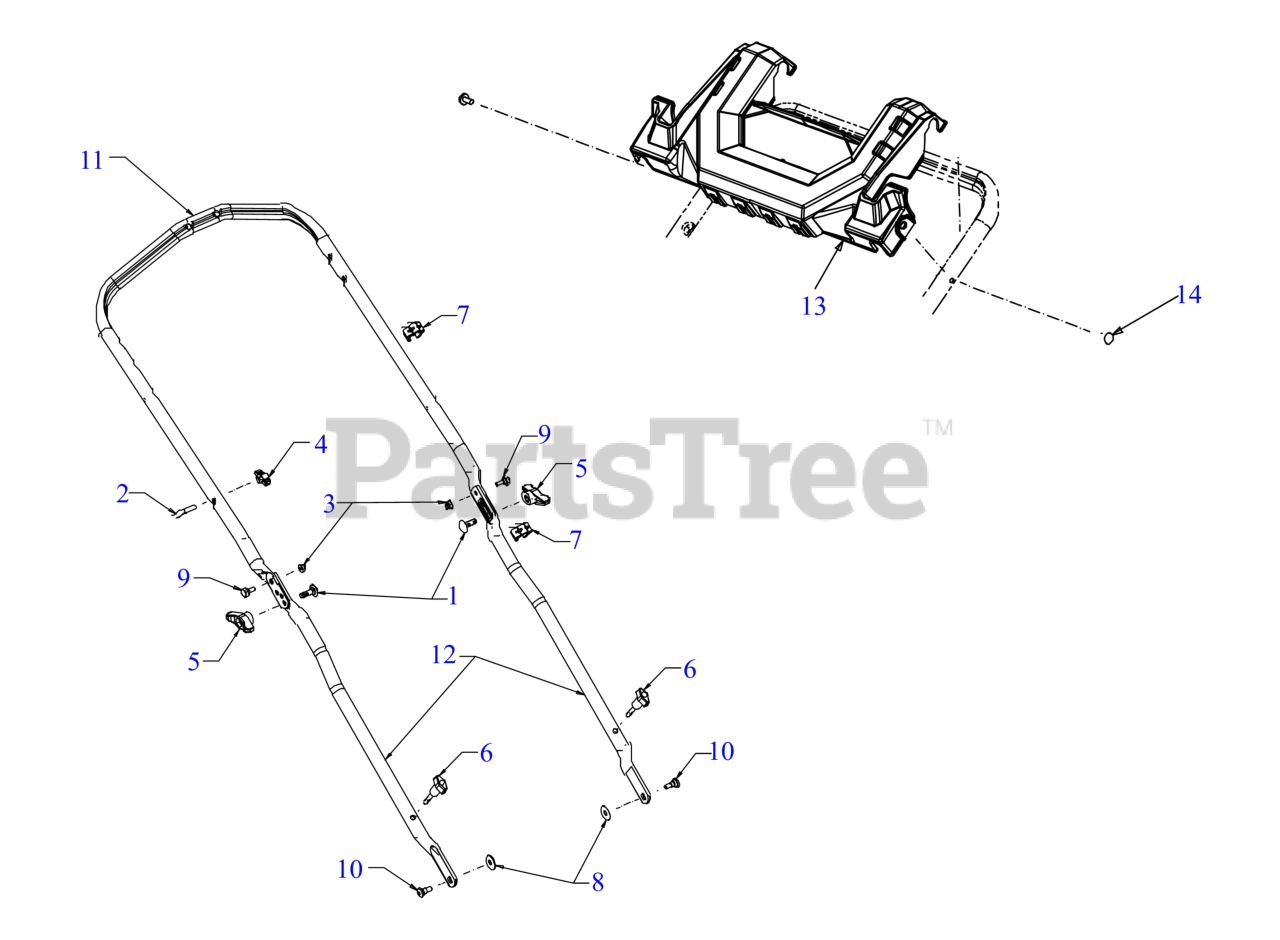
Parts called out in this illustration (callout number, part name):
1	SCREW 5/16-18 x 1.00 GR5
2	EYEBOLT 1/4-20
3	FLANGE LOCK NUT
4	HANDLE KNOB
5	WING KNOB 5/16-18
6	WING KNOB 1/4-20
7	CONDUIT CLIP
8	FLAT WASHER 344X1.00
9	SHOULDER SCREW
10	SHOULDER SCREW .450X .188X 1/4-20
11	UPPER HANDLE
12	LOWER HANDLE (EZ FOLD) (POWDER BLACK)
13	HANDLE CONSOLE
14	SCREW 1/4-14 x .625
